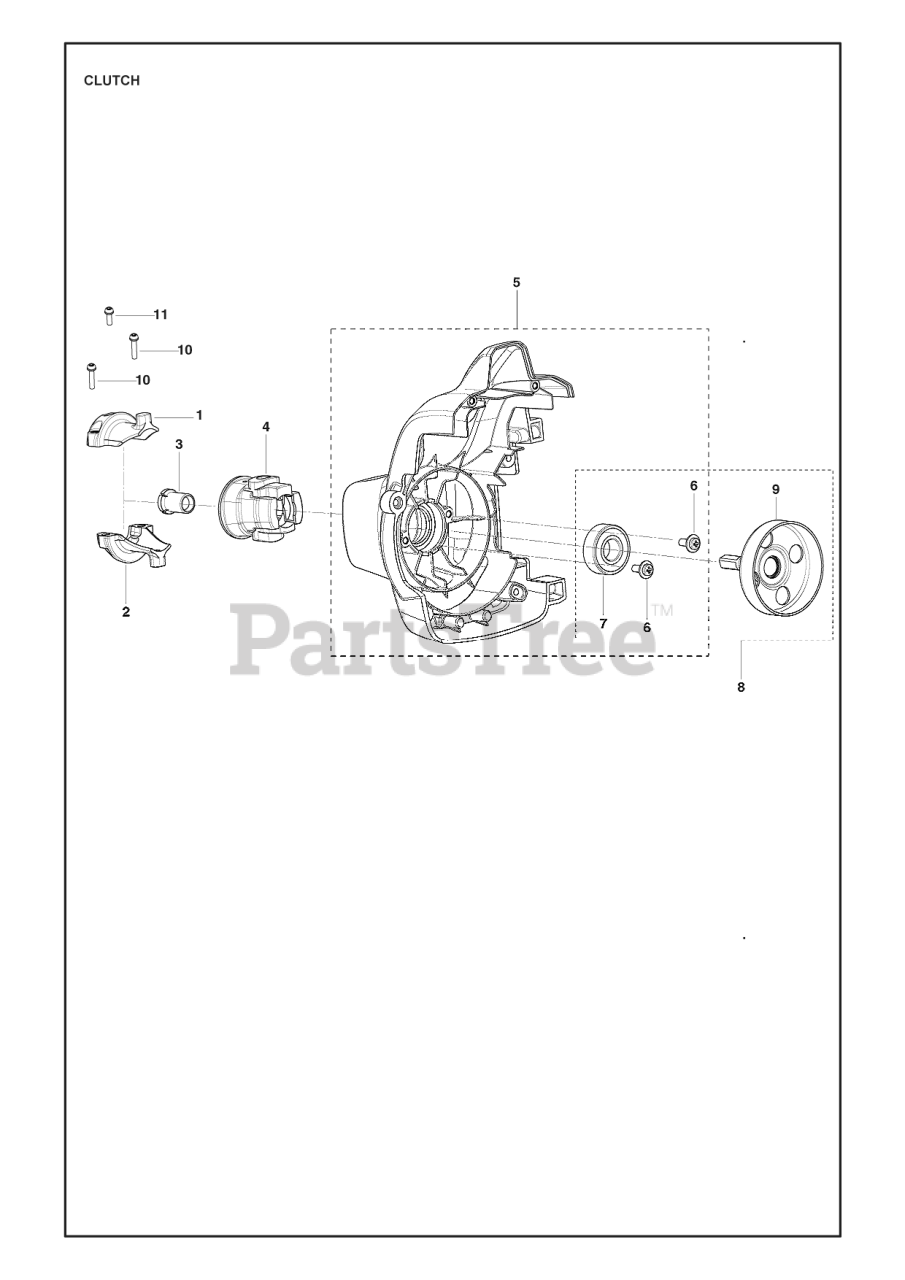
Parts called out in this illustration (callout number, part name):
1	BRACKET UPPER M5X0.8
2	BRACKET LOWER
3	ADAPTOR CLUTCH DRUM
4	CUSHION UPPER
5	FAN HOUSING
8	SERVICE KIT 130 TRIMMER CLUTC
9	CLUTCH ASSY
10	BOLT M5X20 T27
